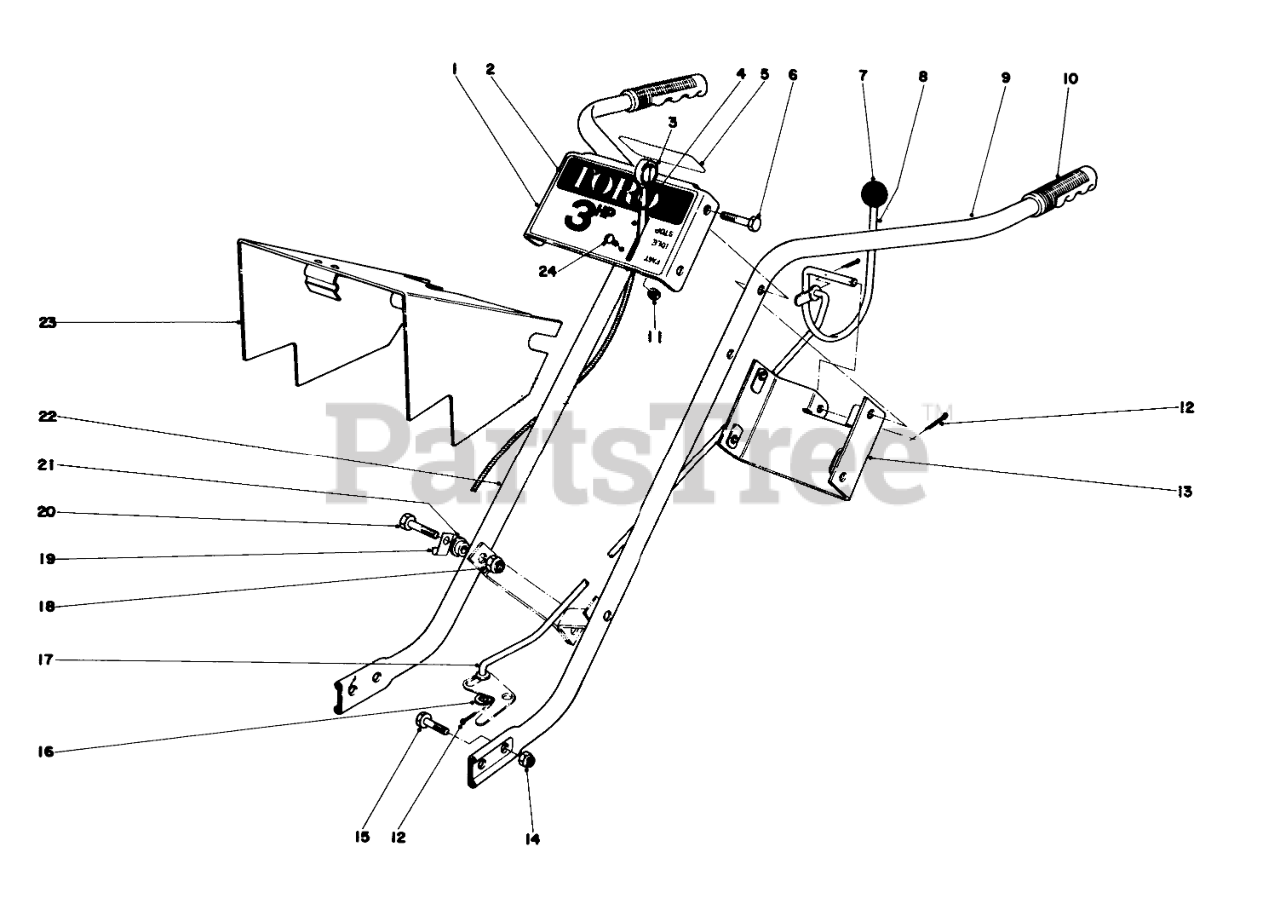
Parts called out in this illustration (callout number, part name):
1	Control Plate
2	Decal
4	Throttle Control
5	Decal Clutch
6	SCREW-HH
7	KNOB-CONTROL
8	Clutch Control
9	Handle L.H.
10	Handle Grip
11	NUT-KEPS
12	PIN-COTTER
13	Handle Brace
14	NUT-LOCK, CONE
15	SCREW-HH
16	WASHER-FLAT
17	Clutch Rod
18	NUT-LOCK, CONE
20	SCREW-HH
21	Spacer
22	Handle R.H.
23	Pulley Cover
24	SCREW-PPH
